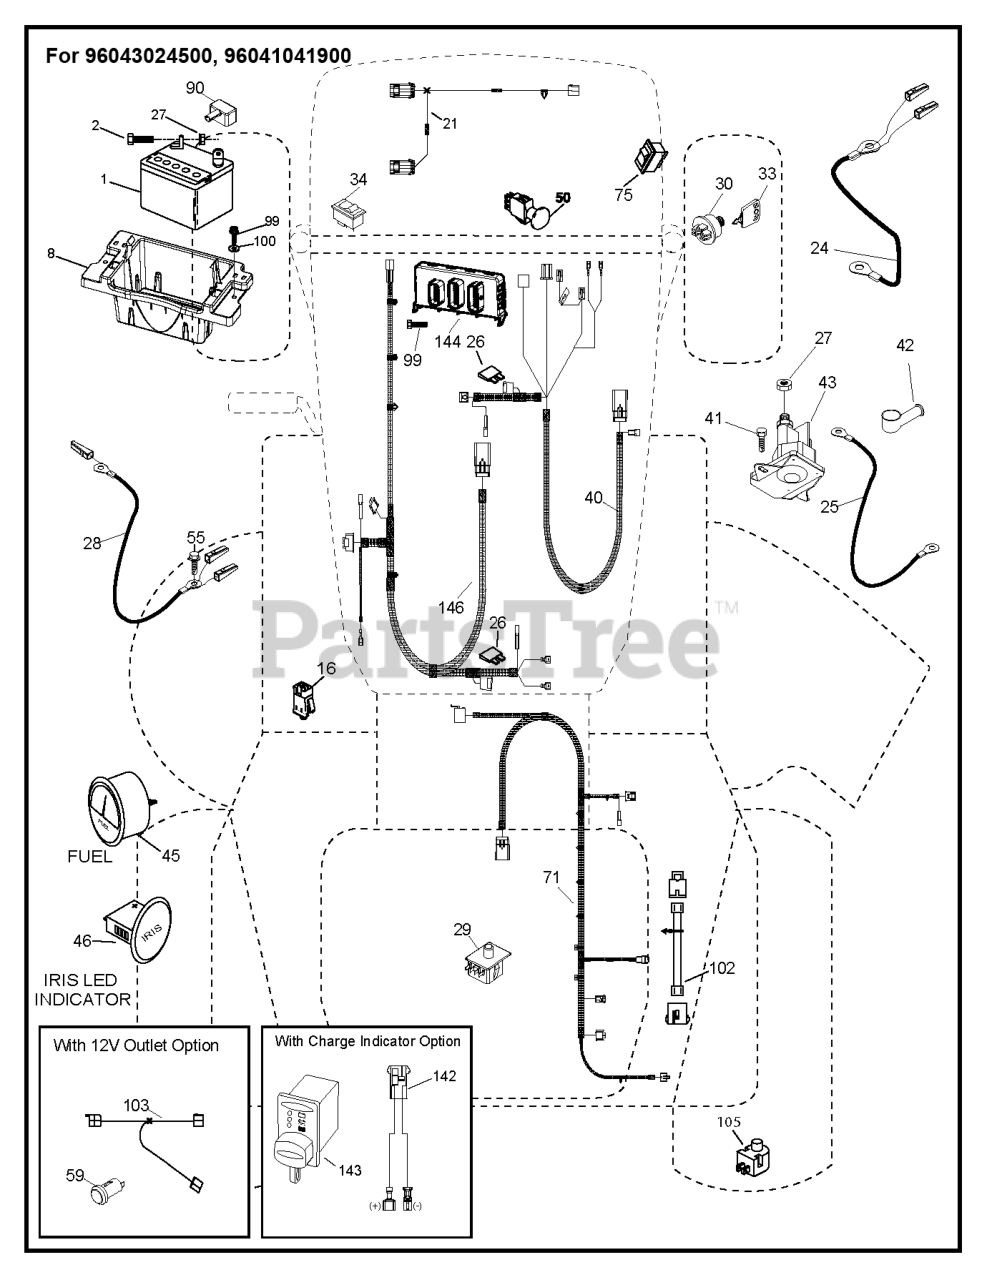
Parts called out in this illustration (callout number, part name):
1	BATTERY.DRY.30.AMP
2	BOLT.HEX.1/4.X.3/4.DICHROMATE
8	TRAY.BATTERY BOX.FRONT
16	SWITCH INTERLOOK PUSH-IN
21	HARNESS.LIGHT W/4152J BULBS
21	HARNESS LIGHT ASSY TRACTOR,
24	PRIMARY CABLE POSITIVE, TWO HA
24	CABLE.FRBATT.W/WIRE.8GA.8
25	CABLE.STARTER.8GA.17.5
26	FUSE 20AMP
27	NUT HEX_LRG FLG_1_4-20_LOCK
28	CABLE.GROUND.21"BLK.8GA.90T
28	GROUND CABLE TWO HARNESS TAPS,
29	SWITCH.SEAT.DELTA.OPC.
29	SWITCH SEAT, 4 PIN NC/NO
30	SWITCH.IGN.DELTA.W.LGH.ROS
33	KEY.CHAIN.BLISTER.PACK.GEN.INT
40	WIRING ASSY DASH, IRIS, 300, T
40	HARNESS.IGN.DSH.W112V.WPORTWIR
42	COVER.TERMINAL.RED
45	Gauges
45	GAUGE.FUEL.LEVEL. ROUND.2"
46	GAUGE.INDCTR.RND.2"FARIA.6ICNS
46	Gauges
50	SWITCH.PTO.8TERMINAL.STD.BLK
55	BOLT.5/16-18UNCX3/4 W/SEMS.BLK
71	HARNESS-CHASSIS SUB
71	WIRING ASSY CHASSIS, IRIS, 300
75	SWITCH.ON/OFF.(DIFF.LOCK)
90	COVER.TERMINAL.BATTERY
99	SCREW HEXWSHR 1/4-20X3/4
102	HARNESS PIGTAIL PCH TEX ROS
105	REVERSE SWITCH
146	WIRING ASSY ENGINE, IRIS, 300,
